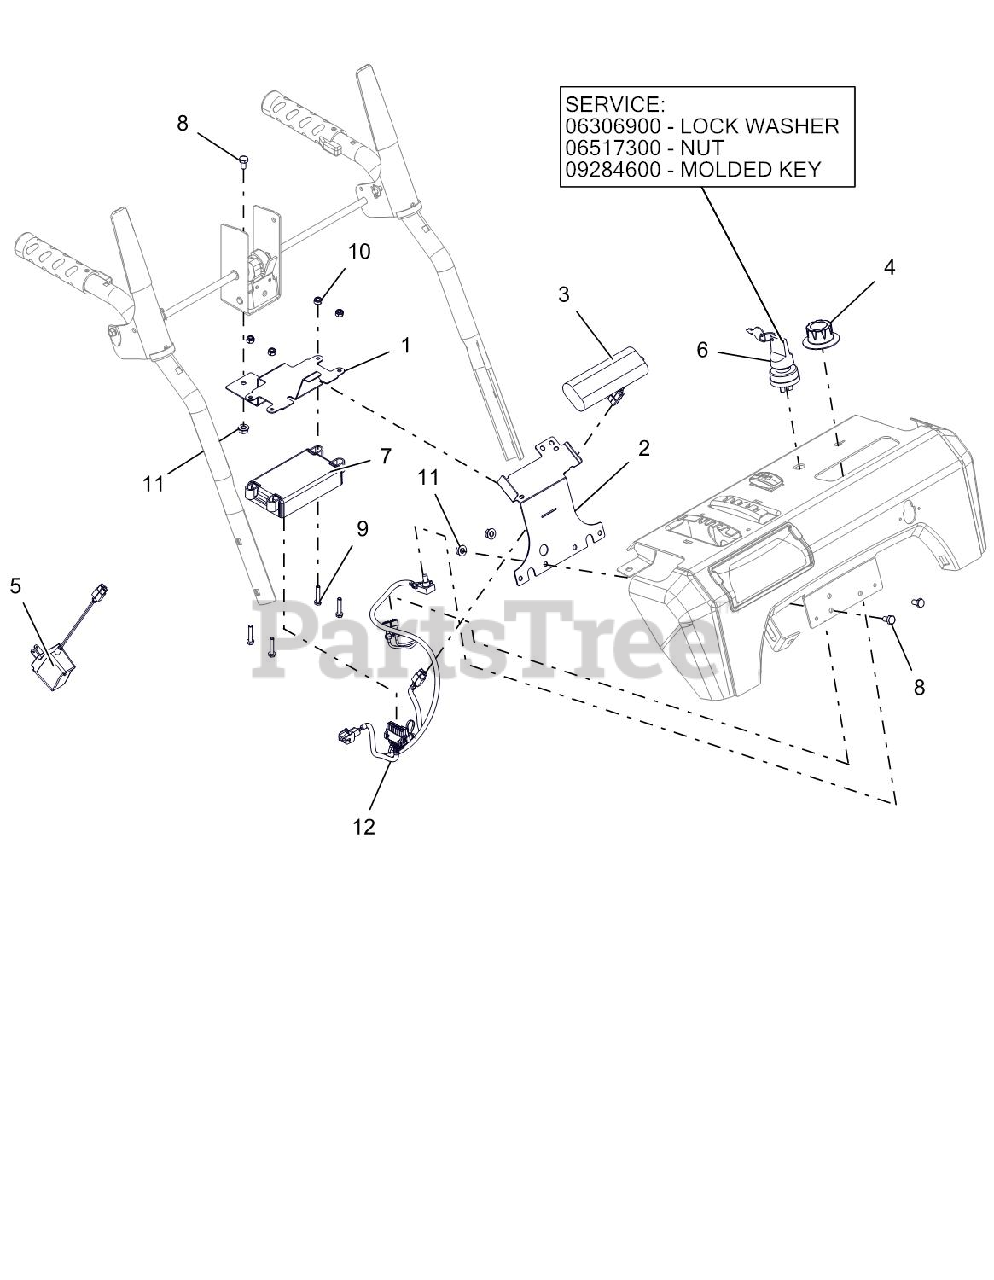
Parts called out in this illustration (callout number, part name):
1	BRACKET, ENGINE EFI-LCT LOWER
2	BRACKET, ENGINE EFI-LCT UPPER
3	BATTERY, SNOW EFI - 7.2V
4	KNOB, CONTROL - 2.063 ID
5	CHARGER, BATTERY - EFI 7.2V
6	NUT-PANEL .625-32 GRECO
6	WSHR-LK-INT .625X.045 YWZC
6	KEY W/ SHIELD
6	IGNITION SWITCH ASM - 2 POS
7	ECU SERVICE LCT/CSI - 369CC
8	@BLT-HEX .25-20X.50 GR5 YWZC
9	@SCR-MCH 10-24X1.00 HWH YWZC
10	@NUT-LK-NYL 10-24 W/INSRT YWZC
11	@NUT-LK-TOP-FLG .25-20 YWZC
12	HARNESS,WIRE - EFI ECU
